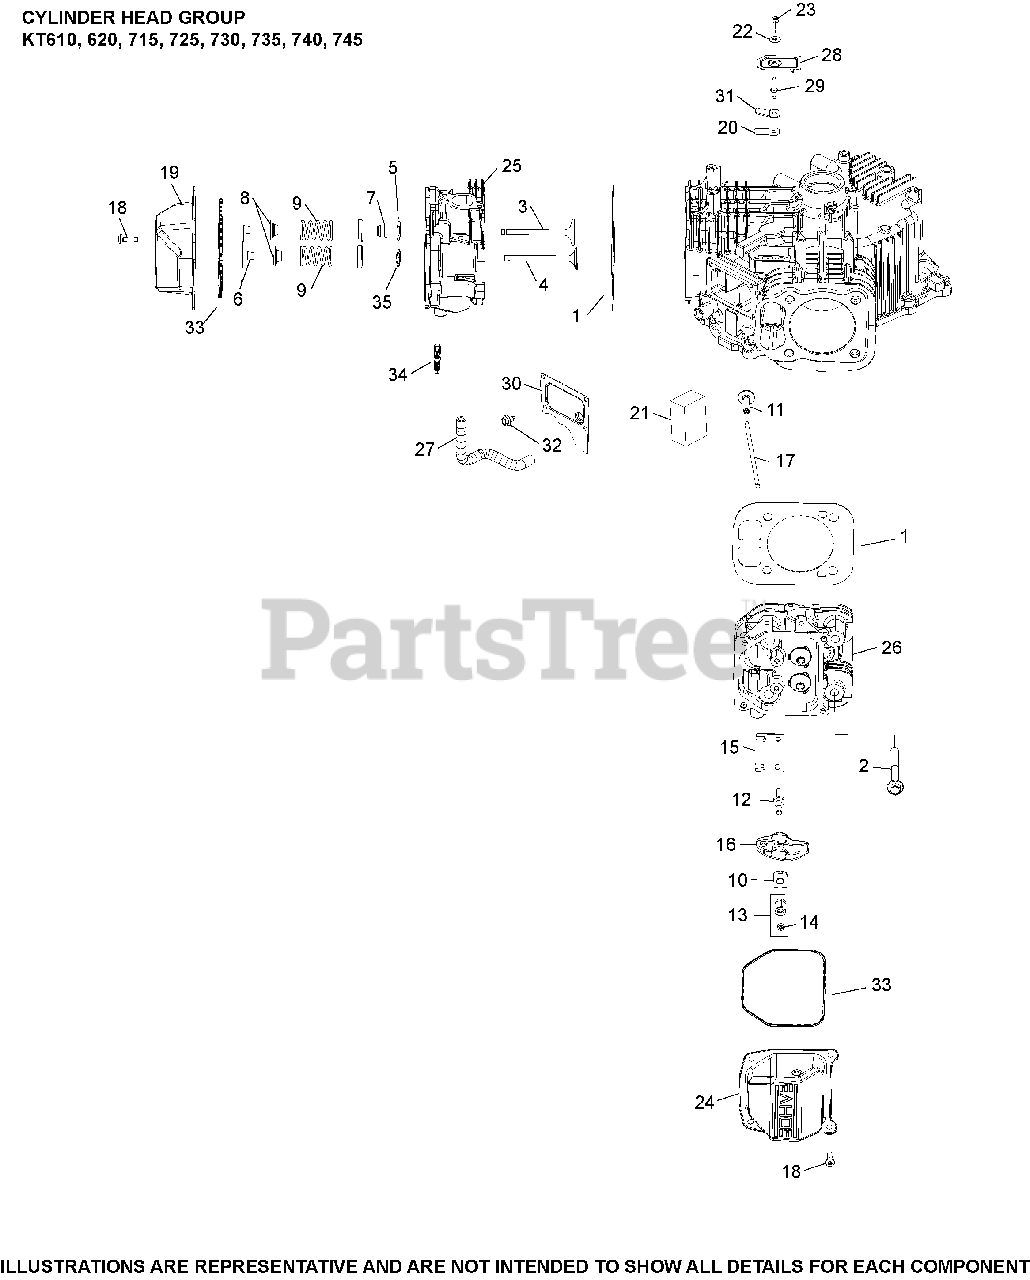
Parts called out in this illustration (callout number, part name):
1	KIT, CYLINDER HEAD GASKET
2	SCREW, FLG M10X1.5X90
3	VALVE, INTAKE
4	VALVE, EXHAUST
5	SPACER (.010")
6	KIT, RETAINER
7	SEAL, VALVE BAND
8	CAP, VALVE SPRING
9	SPRING, VALVE - USE 25 089 17-S
10	PIVOT, ROCKER ARM
12	STUD, ROCKER
13	HEX NUT ASSEMBLY
14	SCREW, SET
15	PLATE, GUIDE
16	ARM, ROCKER
17	ROD, PUSH
18	SCREW, PAN HEAD USE 25 086 660-S
19	COVER, ROCKER STAMPED STEEL
20	REED, BREATHER
21	FILTER, BREATHER
22	WASHER, SEALING
23	NUT, LOCK M5X.8
24	COVER, ROCKER STAMPED STEEL
25	HEAD, ASSEMBLY CYLINDER (#1)
26	HEAD, ASSEMBLY CYLINDER (#2)
27	HOSE, BREATHER
28	COVER, BREATHER REED
30	COVER, BREATHER MEDIA
31	RETAINER, REED
34	STUD, EXHAUST USE 25 072 36-S
